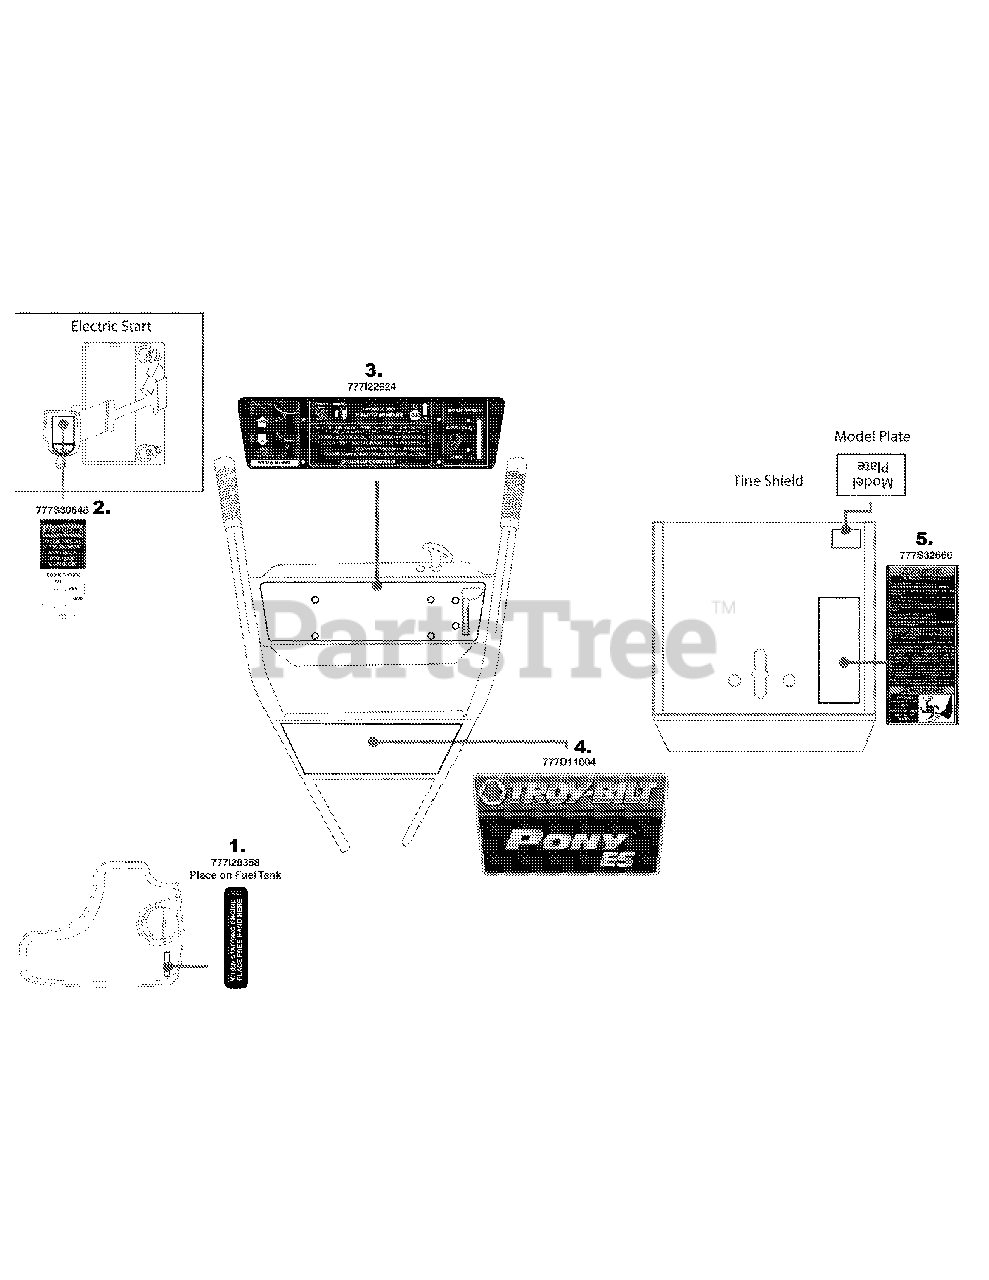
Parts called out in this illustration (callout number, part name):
1	LABEL-PLACE HAND HERE
2	LABEL-ENGINE IGNIT
3	LABEL:TILLER HANDLE:660
4	LABEL-TILLER HANDLE PANEL:PONY
5	LABEL:TILLER TINE SHIELD
